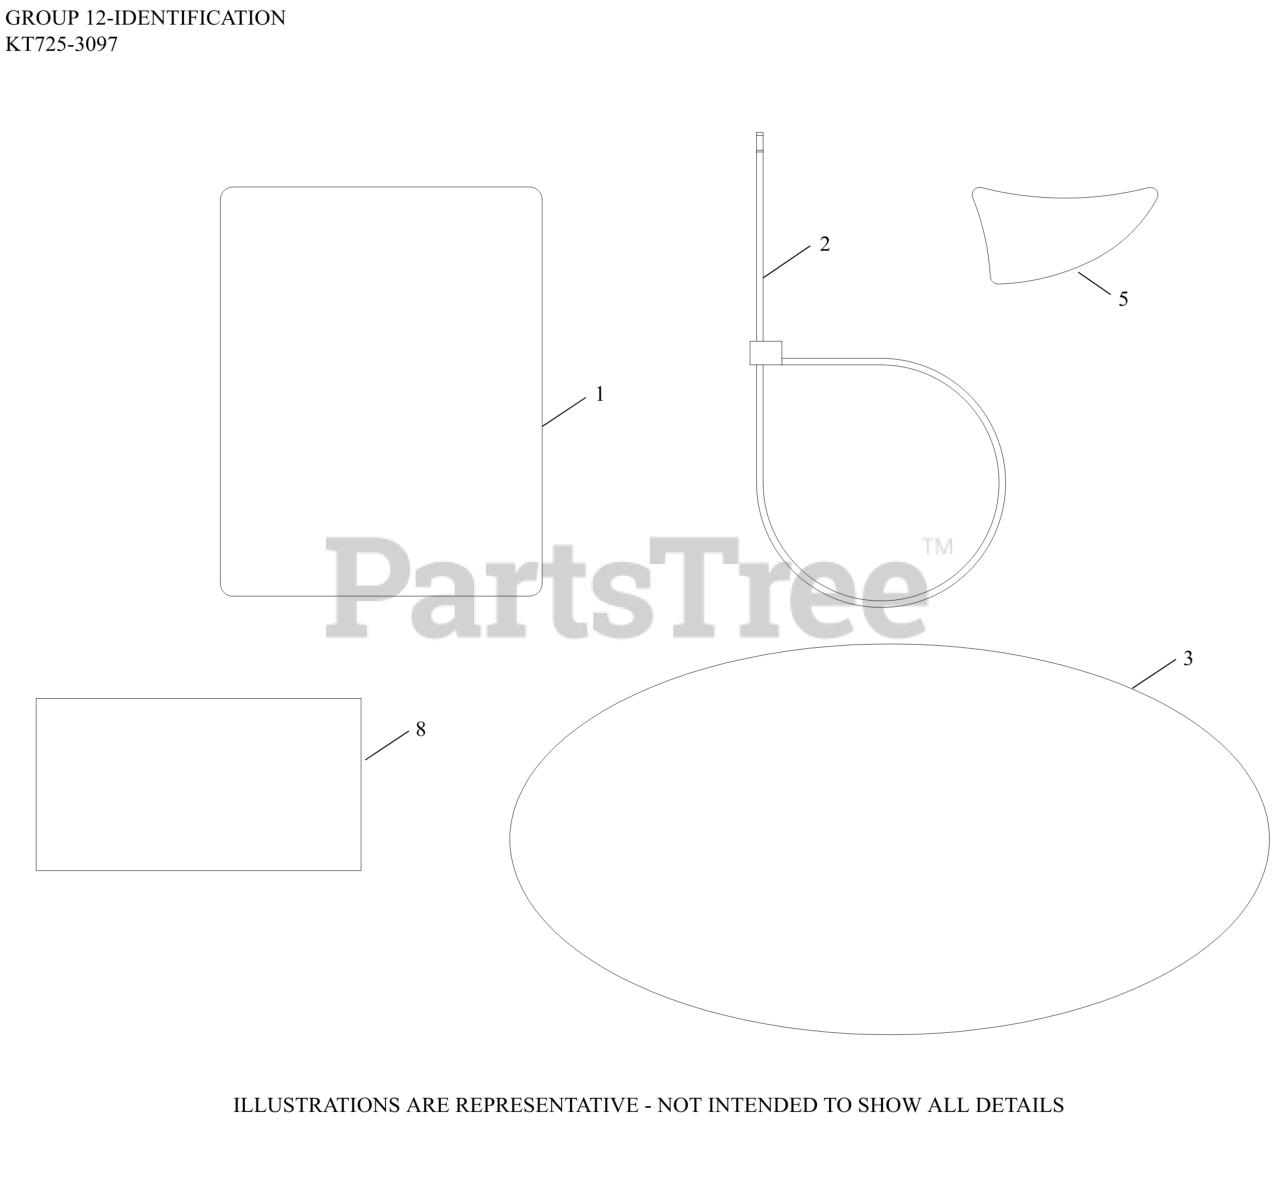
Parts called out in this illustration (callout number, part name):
1	LABEL, CLEAR LAMINATION
3	LABEL, 22HP
5	LABEL, SMART CHOKE
8	DECAL, USA
